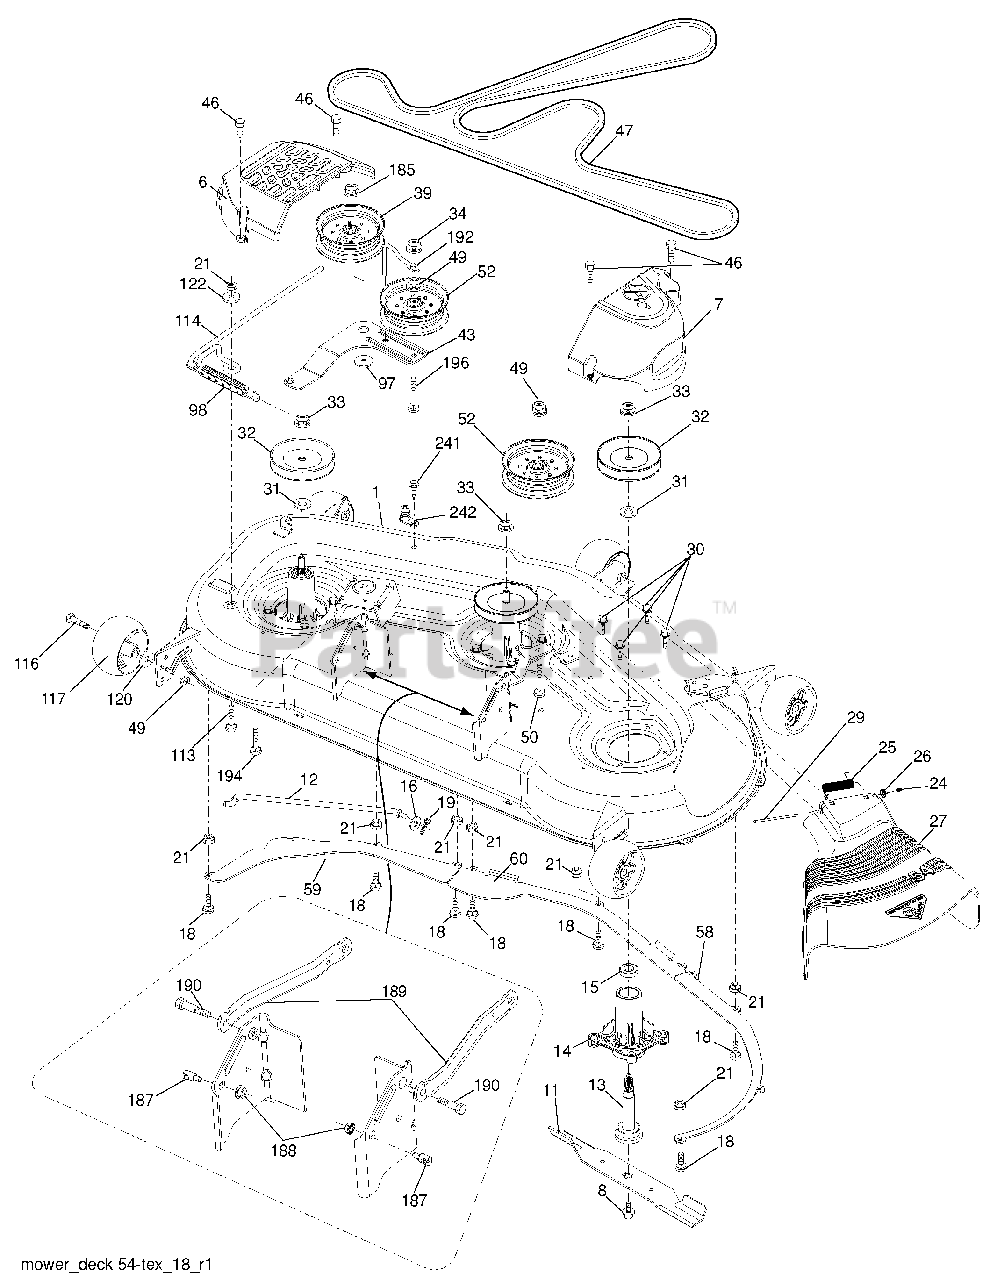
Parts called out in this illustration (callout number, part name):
1	Deck Weldment Mower
6	Cover Mandrel LH
7	Cover Mandrel RH
8	Bolt 7/16 Asm. Blade
11	Blade Bagging
12	Rod Anti-Sway
13	Shaft Asm. w/Lower Bearing
14	Housing, Mandrel
15	Bearing, Ball, Mandrel
16	Washer 13/32 x 13/16 x 12 Ga.
18	Bolt Carr. 5/16-18 x 5/8
19	Pin Cotter 5/16 Bow Tie Lock
21	Nut, Crownlock 5/16-18 unc
24	Cap Sleeve
25	Spring, Torsion
26	Nut, Push
27	Deflector Shield
29	Rod, Hinge
30	Screw, Thdroll Washer Head
31	Washer, Spacer Mower Vented
32	Pulley, Mandrel
33	Nut, Flg. Top Lock
34	Nut Crownlock 3/8-16 unc
39	Pulley, Idler, Stationary
43	Arm, Idler
46	Screw, Thdroll. 1/4-20 x 5/8
47	V-Belt, Mower
49	Nut, Lock Flg. 3/8-16 unc
50	Bolt Rdhd Sqnk 3/8-16 unc x 2
52	Pulley Idler 4.50
58	Baffle Right
59	Baffle Left
60	Baffle Center
97	Washer Hardened
98	Spring Drive
113	Bolt Rdhd Sqnk 5/16-18 x 3/4
114	Rod Tension Relief
116	Bolt, Shoulder
117	Gauge Wheel
120	Washer 13/32 x 1-1/4 x 12 Ga.
122	Bushing Tension Relief
185	Nut Lock Flange 7/16-14 Gr. 5
187	Stud Fastener w/"D" Anti-Rotation
188	Nut Lock Hex Flange 5/16-18
189	Arm Susp. Mower Rear
190	Bolt Shoulder
192	Keeper Belt Idler
194	Bolt Carr Sqnk 3/8-16 x 2-1/4
196	Bolt Rdhd 3/8-16 unc x 2-3/4 Gr. 5
241	Port Washout
242	Screw TT #10-32.5 3/8 FLG
242	Coupling Quick Disconnect
242	Mandrel Asm. Service
242	Blade, 54" Mulching
242	Replacement Mower, Complete
